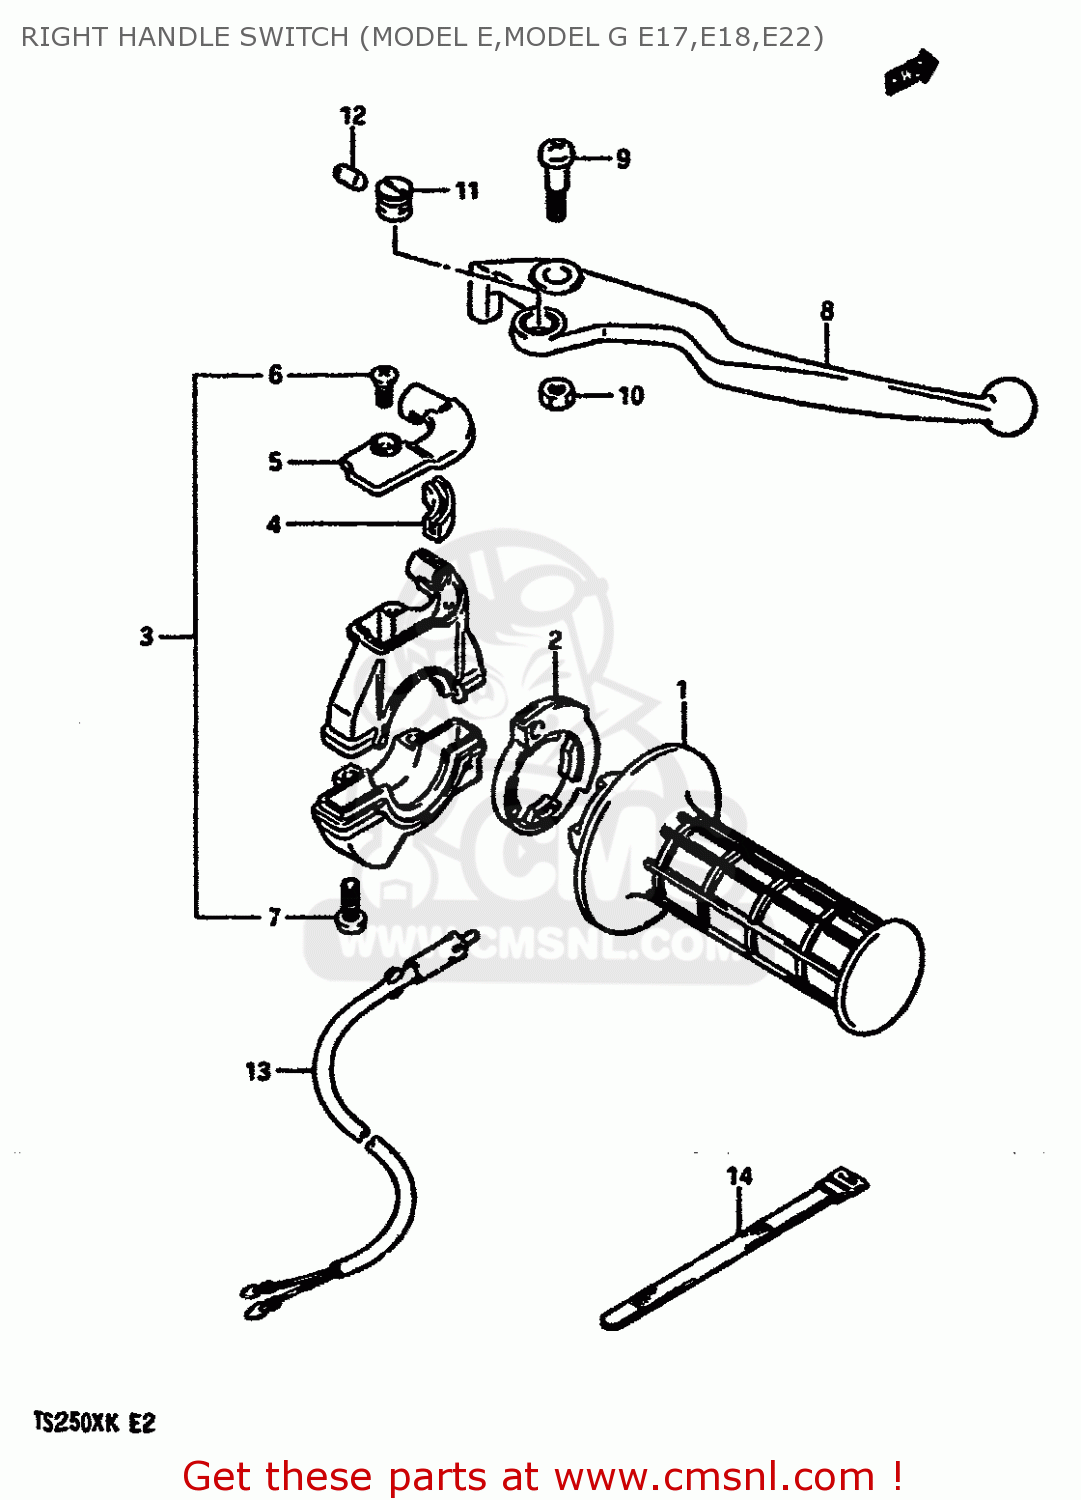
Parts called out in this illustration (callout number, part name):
1	GRIP,THROTTLE
2	ROTOR,THROTTLE GRIP
3	CASE ASSY,THROTTLE
4	GUIDE PIECE,THROTTLE
5	COVER,THROTTLE CASE
6	SCREW
7	SCREW
8	LEVER,BRAKE
9	SCREW
10	NUT 6MM
11	ADJUSTER
12	ROD,PUSH
13	SWITCH ASSY,STOP
14	CLAMP(L:120)
